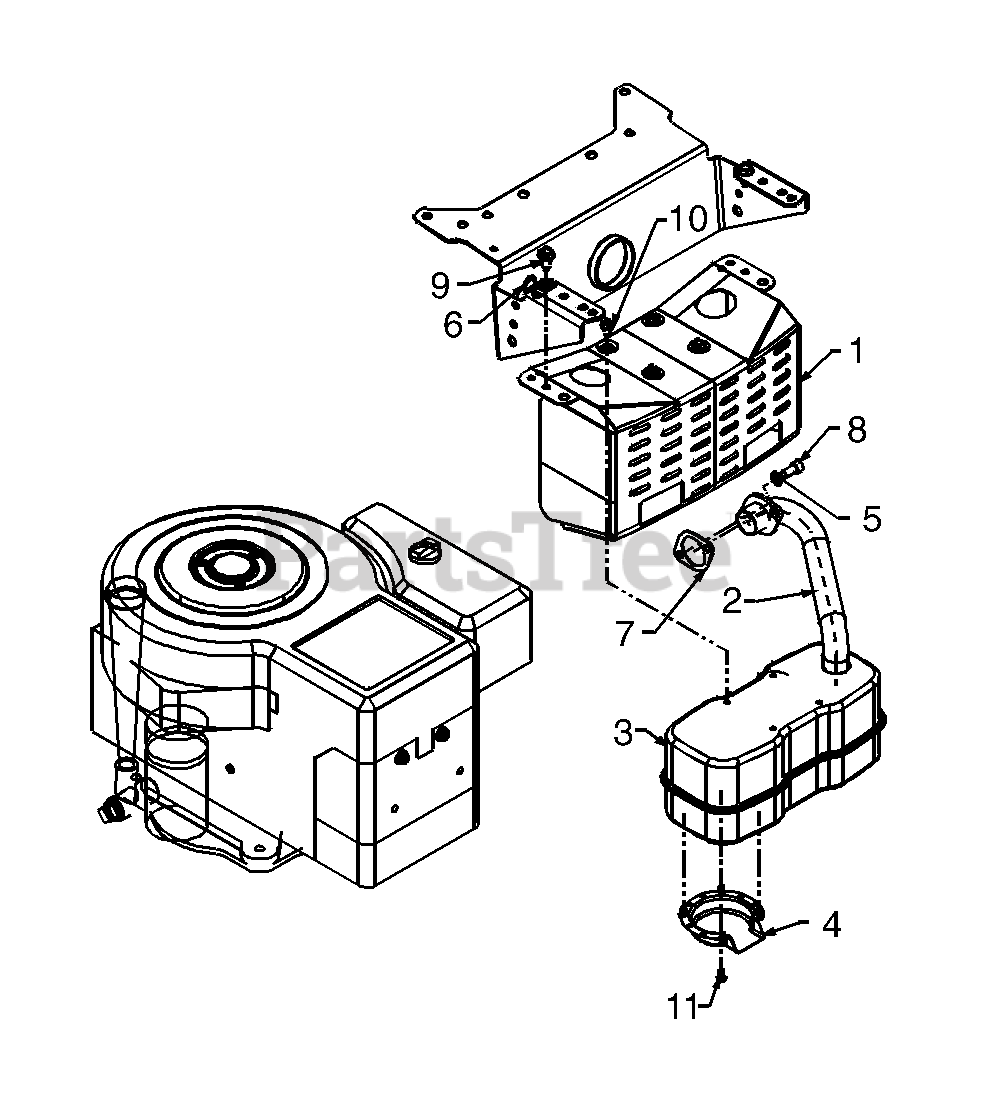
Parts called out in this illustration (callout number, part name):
2	Exhaust Pipe
3	Muffler
4	Muffler Deflector
5	L-Wash. 5/16" I.D.
6	Clamp
7	Exhaust Gasket
8	Socket Hd. Bolt 5/16-18 x .62" Lg.
9	Hex Wash Hd. TT-Tap Scr. 5/16-18 x .62"
10	Hex Wash. TT-Tap Scr. 1/4-20 x .5" Lg.
11	Hex Slot Scr. #8-32 x .38" Lg.
